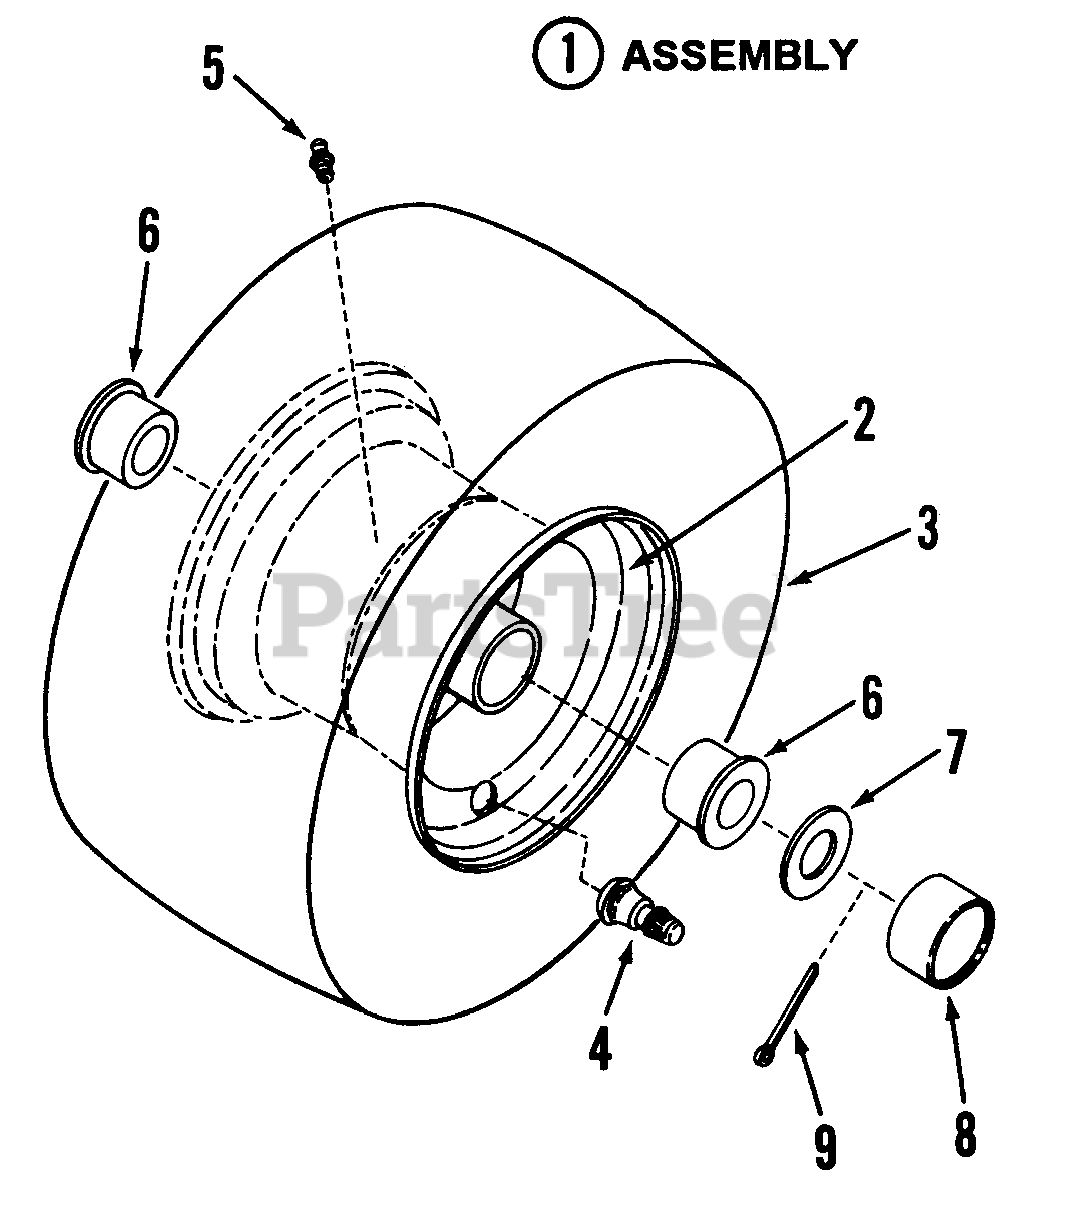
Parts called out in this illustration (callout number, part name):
1	ASSEMBLY, Front Tire 8 Rim
2	RIM, LT16 Front Wheel
3	TIRE, 15 x 6.00 x 6
4	VALVE, Air
5	FITTING, Lube 1/4-28 Tapered Thread
6	BEARING, Wheel
7	WASHER, 49/64 x 1-1/2" Flat
8	COVER, Dust
9	PIN, 5/32 X 1" Cotter
